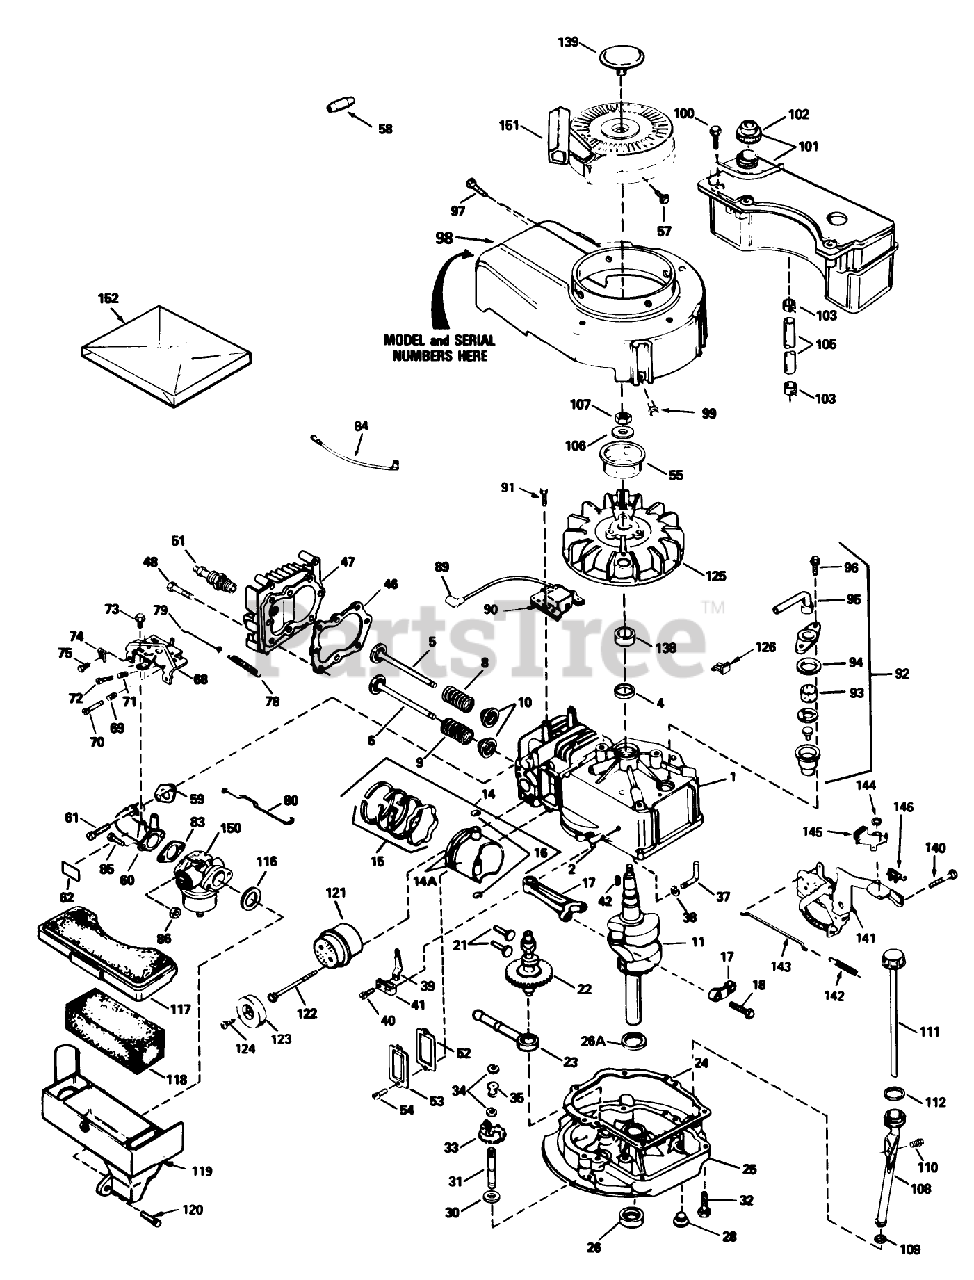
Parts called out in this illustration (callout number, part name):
1	Cylinder Assy. (Incl. #24)
2	Pin-Dowel
4	Seal-Oil
5	Valve, Intake (Std.) (Incl. Ref. #40)
5	Valve, Intake (1/32" oversize)(Incl. No. 40)
6	Valve, Exhaust (Std.)(Incl. No. 40)
6	Valve, Intake (1/32" oversize)(Incl. No. 40)
8	Seal Assy., Intake
9	Spring-Valve
10	Cap-Valve, Spring
11	Crankshaft
14	Piston-Pin Ring Assy. (Std.)(Incl. Ref. #16A, 17 18)
14	Piston-Pin Ring Assembly (.010 oversize)(Incl. Ref. #16A, 17 18)
14	Piston, Pin Ring Assy. (.020 Oversize)(Incl. Ref. #13A, 14, 15)
14A	Piston Pin Assy. (Std.)(Incl. Ref. #14)
14A	Piston Pin Assembly (.010 oversize)(Incl. Ref. #18)
14A	Piston Pin Assy. (.020 Oversize) (Incl. Ref. #14)
15	Ring Set-Piston (Std.)
15	Ring Set, Piston(.0100versize)
15	Ring Set (.020" OS)
16	Ring-Retaining, Piston Pin
17	Rod Assy., Connecting (Incl. Ref. #17)
18	Bolt-Rod, Connecting
21	Lifter-Valve
22	Camshaft(Mech.Comp. Release)
23	Oil Pump ASM
24	Gasket
25	Flange-Mounting (Incl. Ref. #26, 27 39)
26	Seal-Oil
26A	Washer-Thrust
28	Plug Oil Drain
30	Washer-Flat
31	Shaft-Governor
32	Screw (1/4-20 x 1-1/4)
33	Governor Gear ASM
34	Ring-Retaining
35	Spool-Governor
37	Rod, Governor (Incl. No. 36)
38	Washer-Flat
39	Governor Lever
40	Screw
41	Clamp-Lever, Governor
42	Key-Flywheel
46	63573 GIL 42 SNWTHW
47	Head-Cylinder
48	Screw (5/16-18x1-1/2)
51	Spark Plug-Resistor (R J19 L M)
52	Gasket-Breather
53	Cover-Valve
54	Screw
55	Hub-Starter
57	Screw, Hex Hd.
58	Retainer-Starter Rope
59	Gasket-Intake
60	Pipe-Intake (Incl. Ref. #59)
61	Screw (1/4-20 x 1)
62	Decal-Primer
68	Control Assy.-Remote Speed (Incl. Ref. #69 thru 72 76)
69	61709/GIL1515A/95-5
70	Screw
71	Spring-Compression
72	Screw
73	Screw (10-24 x 9/16)
74	Conduit
75	Screw (10-32 x 3/8)
78	Spring Governor
79	2035A67 ADD.ASSEMBL
80	Link-Throttle
83	Gasket
84	Ground Wire
86	Nut and Lock Washer (1/4-28)
89	Cover-Spark Plug
90	Solid State
91	Screw
92	Breather Assy. (Incl. Ref. #46 thru 51)
93	Element-Breather
94	Gasket-Breather
95	Tube, Breaker
96	Screw (10-24 x 9/16)
97	Screw (10-24 x 9/16)
98	Housing-Blower
99	Screw (1/4-20 x 1/2)
100	Screw (10-32 x 35/64)
101	Tank Assembly-Fuel (Incl. Ref. #102)
102	Cap-Fuel
103	Clamp-Line, Fuel
105	Line-Fuel
106	Washer-Belleville
107	Nut-Flywheel
108	Oil Fill Tube
109	Gasket
110	Screw (10-32 x 1/2)
111	Dipstick
112	O-Ring
116	Gasket-Cleaner, Air
117	Cover Air Cleaner
118	Filter-Air Cleaner
119	Body Air cleaner
120	Screw
121	Muffler (Incl. Ref. #122)
122	Screw
123	Cover-Muffler
124	Screw (8-32 x 3/8)
125	Flywheel
126	Clip-Wire
138	Spacer
139	Plug Starter
140	Screw (1/4-20 x 3/8)
141	Bracket-S.E. Brake
142	Spring-Extension
143	Link-Control
144	Ring-Retaining
145	Lever-Brake
146	Terminal
150	Carburetor (Incl. Ref. #83)
151	Starter-Rewind
152	Gasket Set
